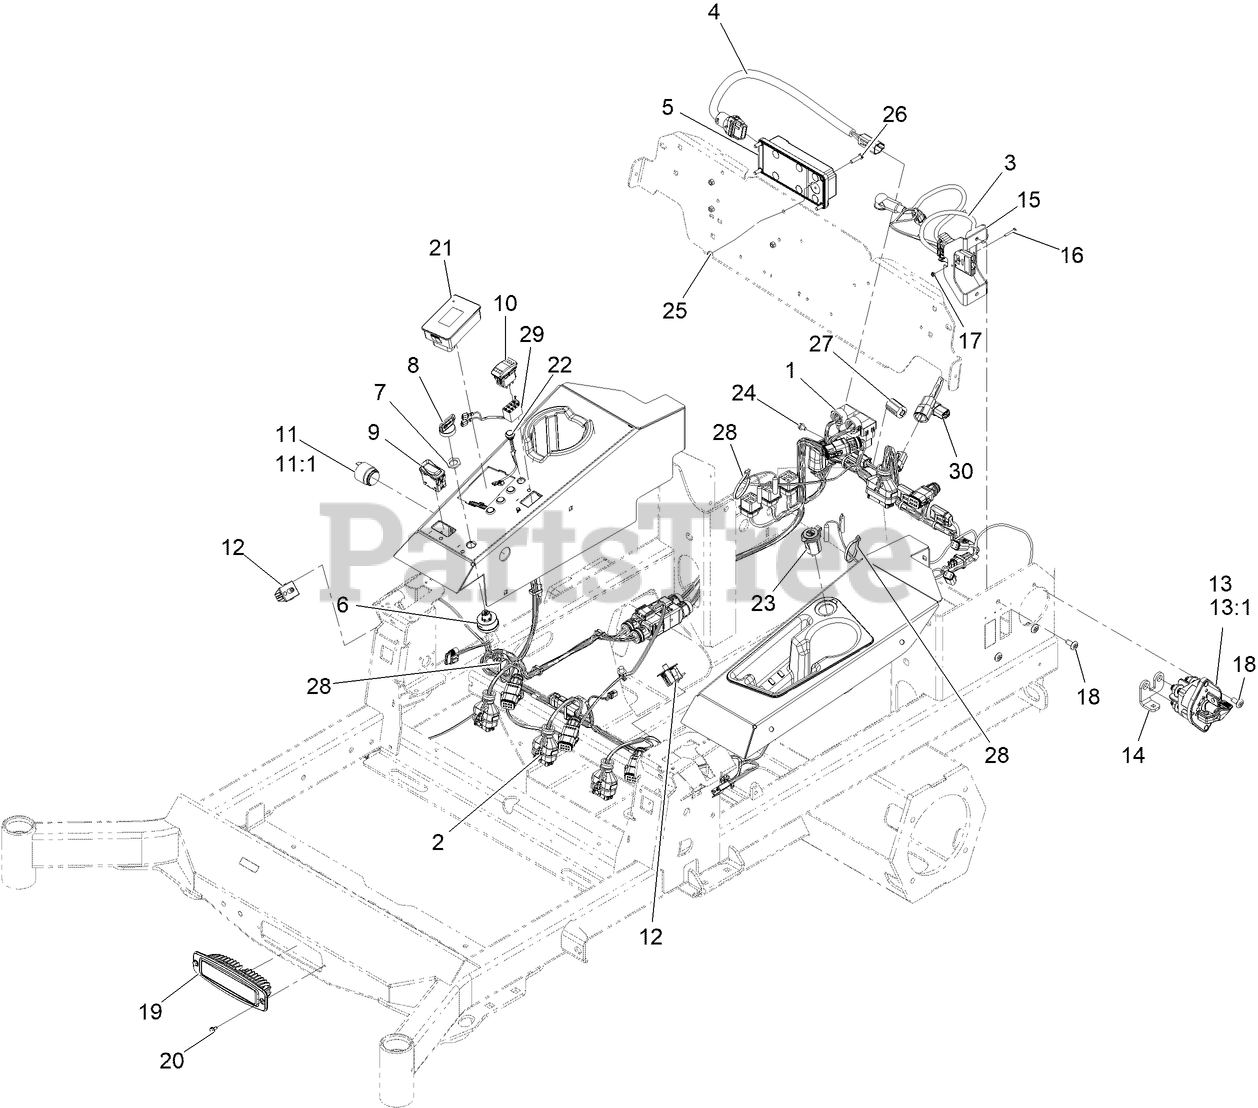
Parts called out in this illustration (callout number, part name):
1	HARNESS-WIRE, MAIN
2	HARNESS-WIRE, DECK
3	HARNESS-WIRE, CHARGER PORT
4	HARNESS-WIRE
5	CONTROLLER
6	SWITCH-KEY, SPST
8	KEY-IGNITION
9	SWITCH-ROCKER, ON-NONE-ON
11	Audio Alarm ASM
11:1	Nut-Plastic, Knurled
12	SWITCH-PLUNGER, ON-(ON)
13	SWITCH-DISCONNECT
14	BUSBAR-2, SWITCH
15	BRACKET-CHARGER, DUAL
16	SCREW-HH
17	NUT-HEX
19	MOUNT-FLUSH, LIGHT
20	SCREW-HWH
21	MODULE-DISPLAY
22	SWITCH-PUSHBUTTON
23	PORT-POWER, USB
24	SCREW-HWH
25	NUT-LOCK
26	SCREW-HSBH
27	FERRITE, SNAP-ON
28	TIE-CABLE
29	Harness-Light Switch Jumper
30	HARNESS-WIRE, JUMPER
